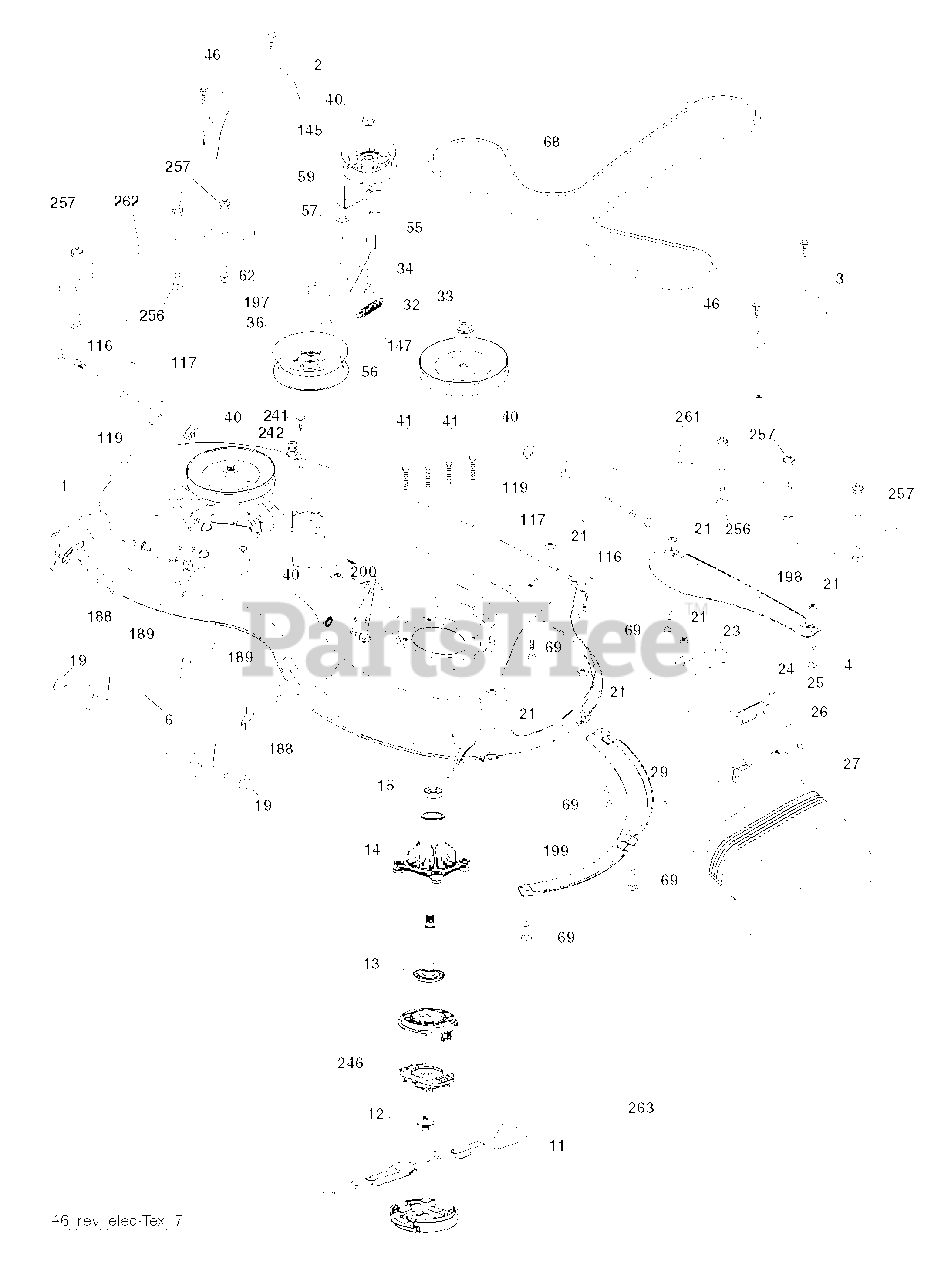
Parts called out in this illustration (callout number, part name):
1	HOUSING.46.WELDMNT.TTR.2GW.498
2	COVER.MANDREL.LH.46"
3	COVER.MANDREL.RH.46"
4	BOLT
6	ARM.SUSPENSION.MOWER.R
11	BLADE.REVOLTION.46"BAGER.PT43
12	SCREW.SEMS.7/16-20X1.HEX.HEAD
13	SHAFT ASM.REV.TALL.N/GREASEBL
14	HOUSING.MANDREL.REV.TALL.N/GRS
19	BOLT.SHOULDER
21	LOCKNUT
23	BRKT.DEFLECTOR.38"2005+
24	CAP-SLEEVE LT
25	SPRING.TORSION.DEFLECT
26	NUT PUSH M
27	SHIELD.DEFLECTOR.MOWER.46"BLAC
29	ROD.HINGE
32	PULLEY.MANDREL.5.438.PD
33	NUT.FLANGE.LOCK.TOP
34	BOLT.3/8-16X1.50
36	PULLEY.IDLER.2006
40	NUT LOCK FLG 3/8-16 UNC
41	BOLT.HEX.WASHR.HED.313-18X1.19
46	SCREW.1/4-20X5/8
56	SPACER.RETAINER
57	SCREW 3/8-16X1
59	GUARD, BELT
62	BOLT-HEX EAK
68	V-BELT
69	BOLT
116	BOLT M
117	WHEEL.GAGE.HALF.SPOKED
119	WASHER
145	PULLEY.IDLER.48"PRIMARY
147	SPRING.MOWER.DRIVE.ELECTRIC
188	STUD.FASTNER.W/ANTI-ROTATE
189	NUT LOCK HEX FLANGE 5/16-18
197	WASHER
198	BAFFLE CENTER FRONT
199	BAFFLE FRONT RH
200	WASHER.13/32 X 1 X 1/2.11GUARD
241	SCREW.TT.#10-32X.5.3/8.FLANGE
242	PORT.WASHOUT
246	HOLDER.BLADE.REVOLUTION
256	SCREW.BUTTONHEAD.1/4-20X1
257	NUT T
261	PLATE.REINFORCE.46.BOLT.ONX431
262	PLATE.REINFOR.46.SIDEBOLT.X431
263	CAP.REVOLUTION ASM
